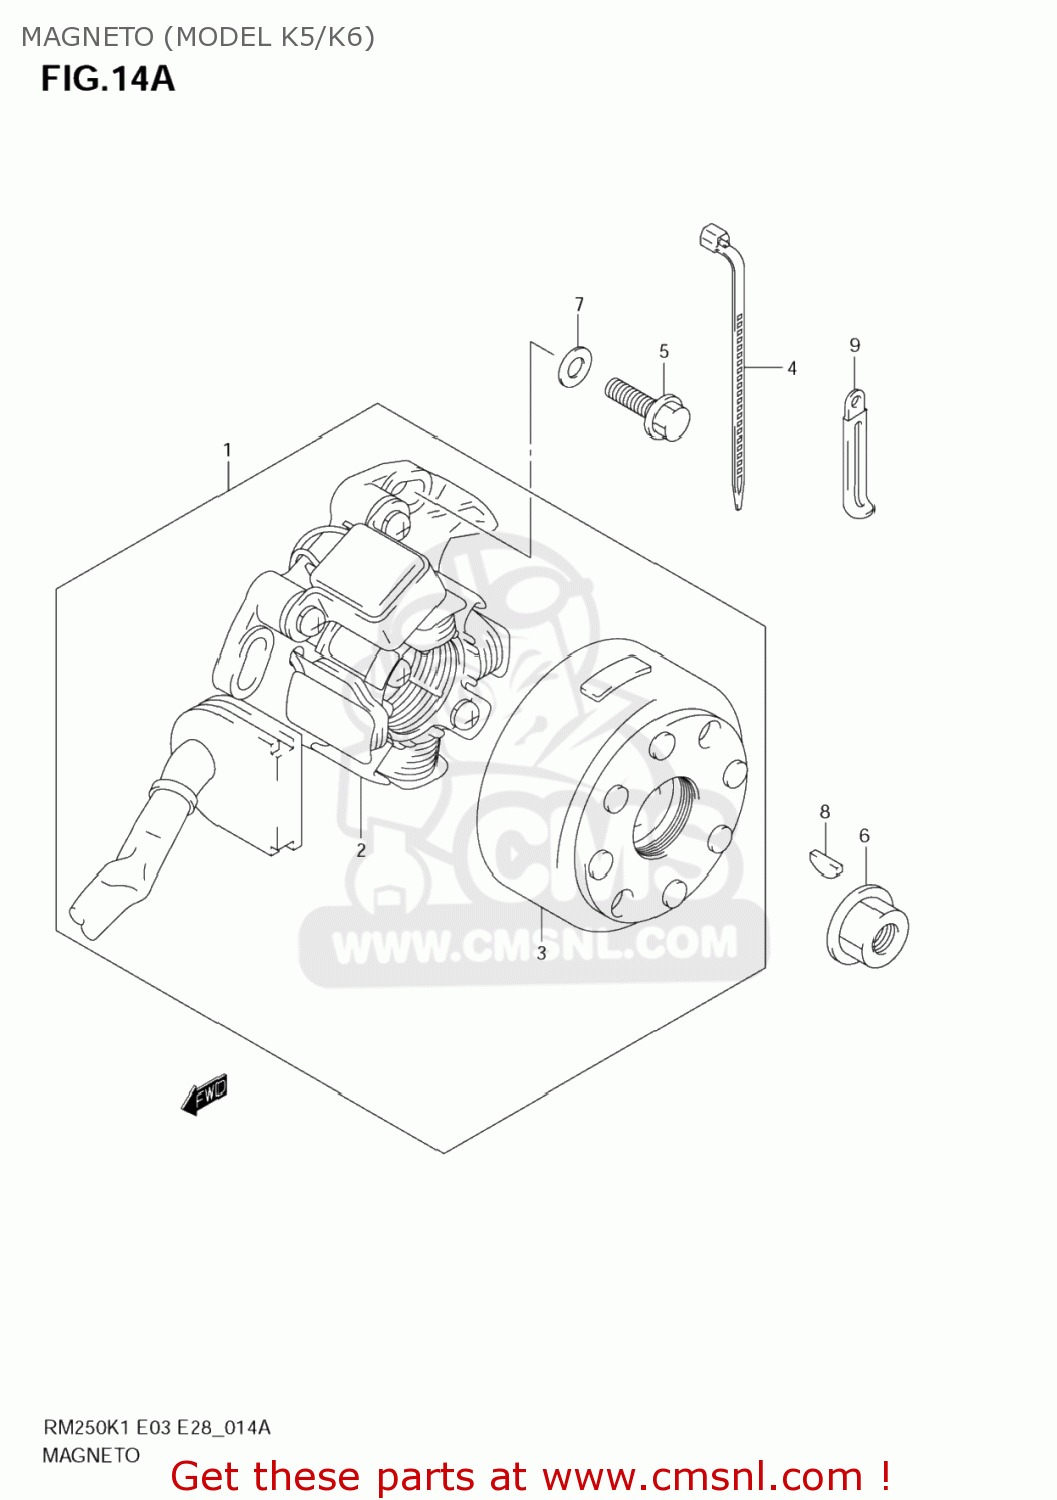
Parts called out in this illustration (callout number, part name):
1	MAGNETO ASSY
2	STARTER ASSY
3	ROTOR ASSY
4	CLAMP(L:165)
5	BOLT,6X20
6	NUT
7	WASHER
8	KEY
9	CLAMP(L:80)
